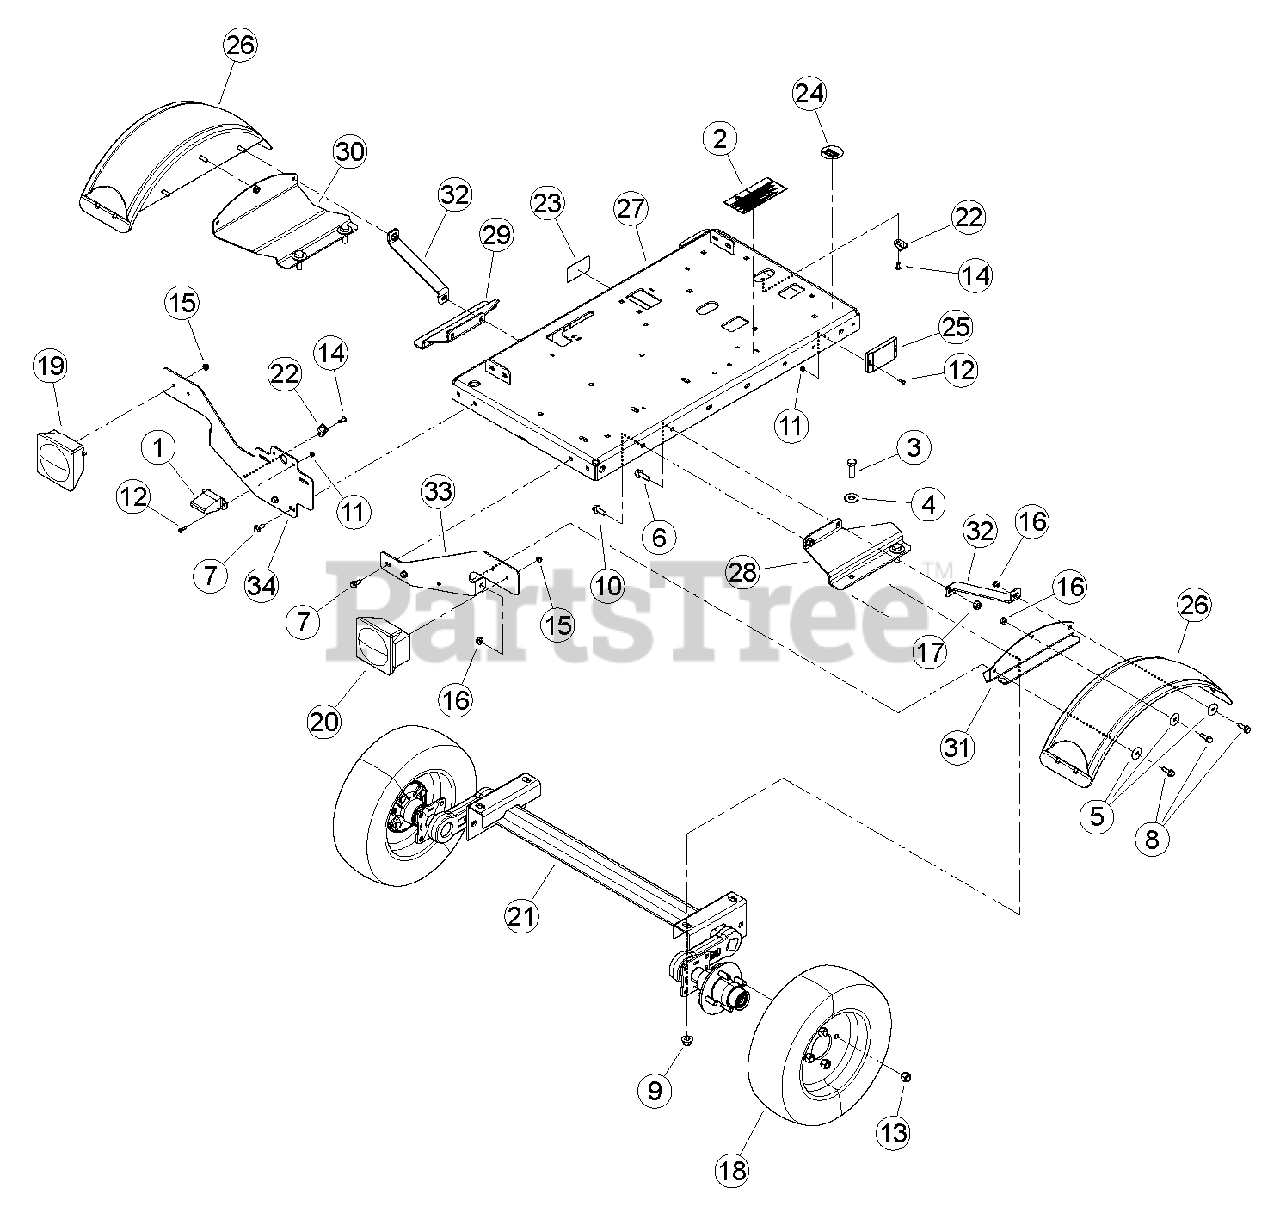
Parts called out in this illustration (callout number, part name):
1	LIGHT, LICENSE PLATE
2	DECAL, MUTILINGUAL MANUAL
3	BOLT, 1/2-13 X 1-1/2 HEX HD GR5
4	WASHER, 1/2 FLAT
5	WASHER, 5/16" FENDER ZP
6	BOLT, 3/8 X 1-1/4 FLANGE NC
7	BOLT, 5/16 X 3/4 FLANGE NC
8	BOLT, 5/16 X 1 FLANGE NC
9	NUT, 1/2-13 NYLOCK FLANGE
10	BOLT, 3/8 X 1 FLANGE NC
11	NUT, 10/24 NYLOCK TYPE NM ZP
12	SCREW, #10-24 X 3/4" PAN HD PH ZP MCH
13	NUT, 1/2-20 WHEEL
14	RIVET, AL BLIND 1/4 X 3/4 DOME HEAD
15	NUT, 1/4-20 NYLOCK FLANGE
16	NUT, 5/16-18 NYLOCK FLANGE
17	NUT, 3/8-16 NYLOCK FLANGE
18	ASSEMBLY, TIRE + WHEEL 4.80-8
19	LIGHT, LH TAIL
20	LIGHT, RH TAIL
21	AXLE, 1000 LB TORSION
22	CLAMP, CABLE MOUNT
23	DECAL, 5.30-12 LOAD RATING
24	DECAL, NATM COMPLIANCE
25	KIT, LED AMBER LIGHT
26	FENDER, BLACK PLASTIC DRILLED
27	WELDMENT, CHIPPER TRAILER
28	SUPPORT, AXLE FENDER RH
29	SUPPORT, AXLE FENDER LH
30	SHEET, MOUNT FENDER LH
31	SHEET, MOUNT FENDER RH
32	BRACKET, FENDER SUPPORT
33	BRACKET, LIGHT RH
34	BRACKET, LIGHT LH
